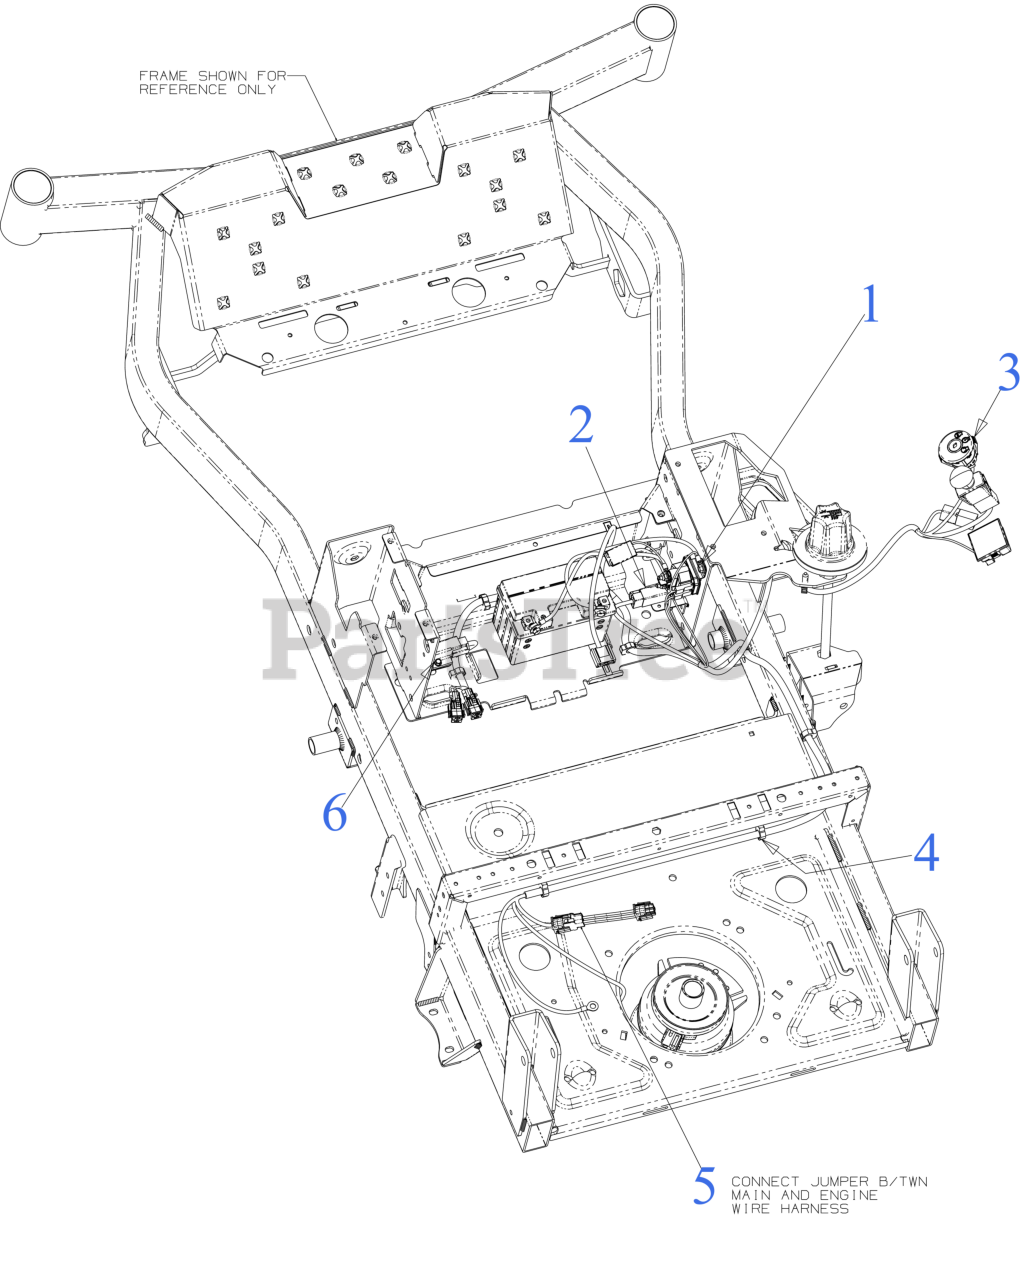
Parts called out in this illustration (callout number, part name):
1	SCREW 1/4-20X.625
2	INTERLOCK SWITCH (NO/NC)
3	KEY SWITCH (3 POS 6 PIN)
3	IGNITION KEY
4	MAIN HARNESS
4	12V RELAY 35A
4	NEUTRAL SWITCH
5	ADAPTER HARNESS (KH CONFIDANT)
6	SHOULDER SCREW
